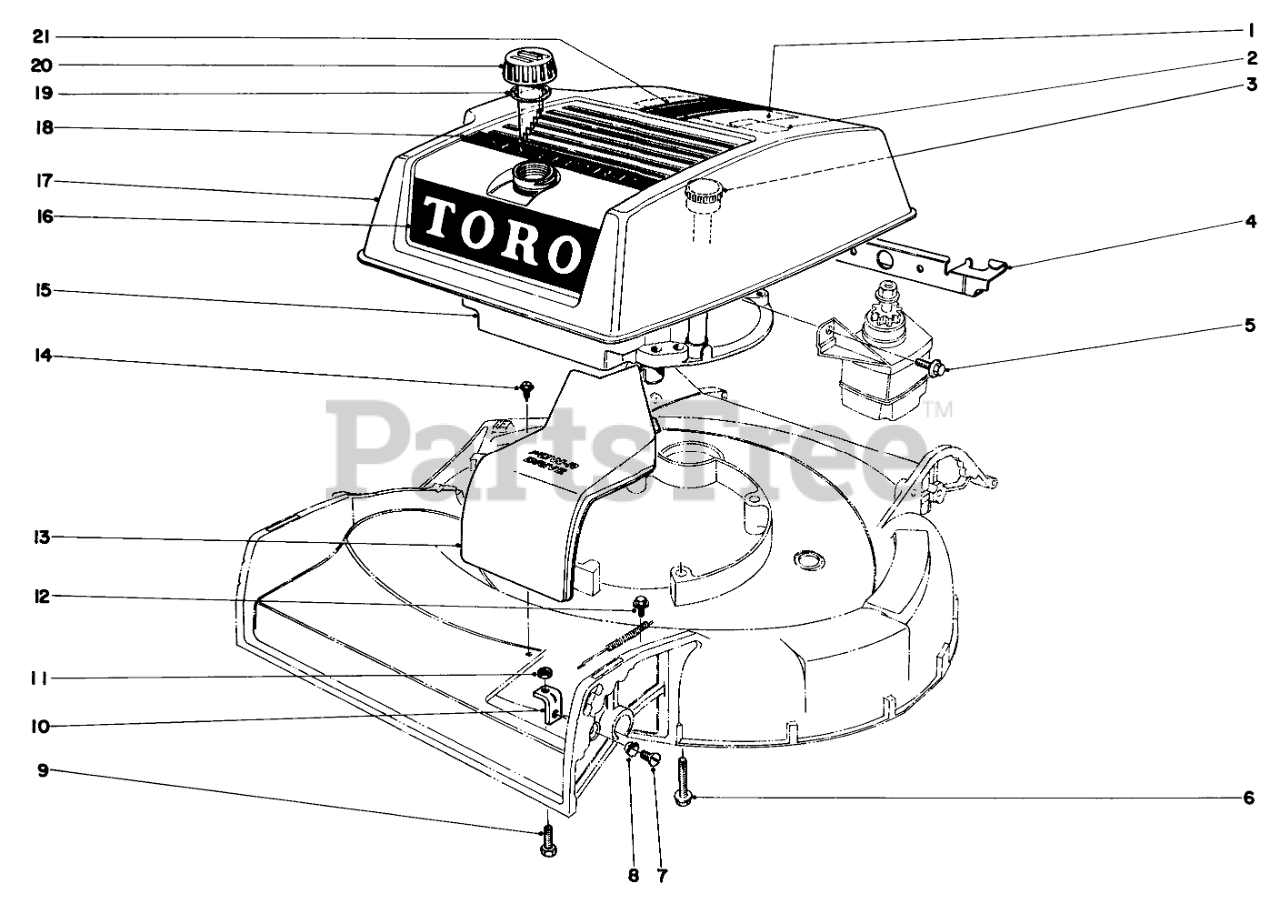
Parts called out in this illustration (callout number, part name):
1	Decal-Maintenance
2	Decal Caution
3	Dip Stick
4	Shroud Bracket
5	SCREW
6	3/8-16 X 2-3/4 CAPSCR
8	Lockwasher
9	SCREW
10	ADJ BRACKET
11	NUT-JAM
12	Screw
13	Belt Drive Cover
14	SCREW-HWHTF
15	Engine
16	Decal-Toro
17	Shroud
18	Decal-Key-Lectric
19	Gasket
20	Gas Cap (Incl. Ref. No. 18)
21	Decal
